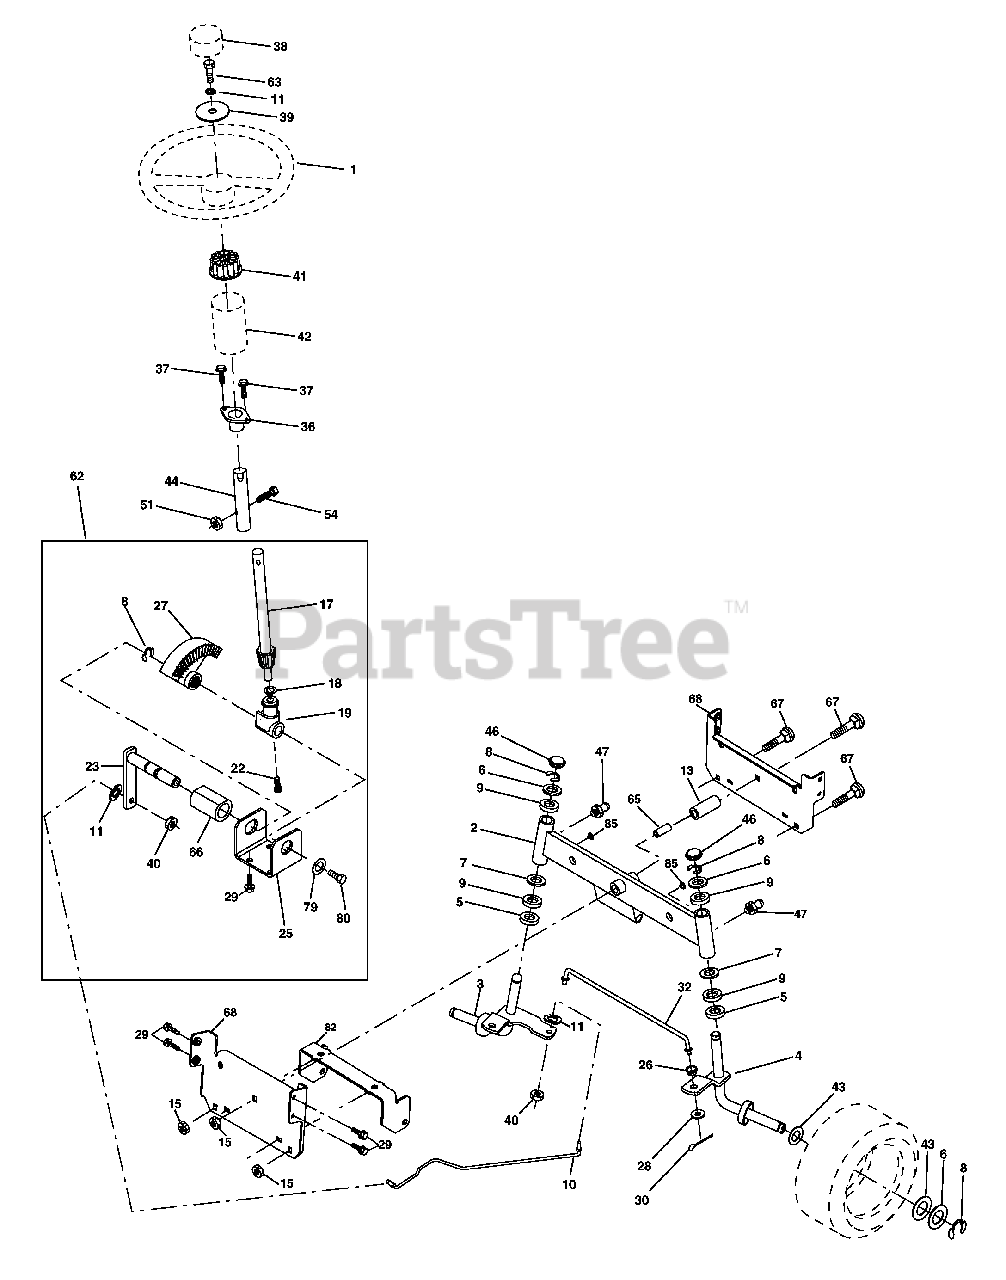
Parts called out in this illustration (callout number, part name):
1	Wheel Steering Ayp/P/L Blk
2	Axle Asm
3	Spindle Asm LH
4	Spindle Asm RH
5	Bearing Race Thrust Harden
6	Washer 25/32 X 1-5/8 X 16 Ga
7	Washer 27/32 X 1-1/4 X 16 Ga
8	Ring Klip #t5304-75
9	Bearing Col Strg Blk
10	Link Drag Extended Stamped
11	Washer Lock Hvy Hlcl Spr 3/8
13	Bearing Axle
15	Nut Lock Flange 5/8-11 Unc
17	Shaft Asm Strg
18	Washer Thrust 515x 750x 033
19	Support Shaft
20	Washer Shim 1/4 X 5/8 X 062
22	Screw Hex Socket 1/4-20 x 5/8
23	Shaft Asm Pittman
25	Bracket Steering
26	Bushing Link Drag Blk LR
27	Gear Sector
28	Washer 13/32 X 7/8 X 16 Ga
29	Screw Thdrol 3/8-16x3/4 Ty-tt
30	Pin Cotter 1/8 X 3/4 Cad
32	Rod Tie Wire Form 19 75 Mech
36	Bushing Strg 5/8 Id Dash
38	Cap Wheel Steer Ayp
39	Washer 13/32 X 2-3/8 X 8 Ga
40	Nut Lock Center 3/8-24un
41	Adaptor Wheel Strg
42	Boot Dash Mtl Steering Blk
43	Washer 25/32 X 1 1/4 X 16 Ga
44	Extension Steering
46	Cap Spindle Fr Top Blk
47	Fitting Grease
51	Nut Lock Hex W/Ins 5/16-18
54	Bolt Fin Hex 3/8-16unc x 1-1/4
62	Kit Steering Assembly Service
63	Bolt Fin Hex 3/8-16unc x 1 Gr.5
65	Spacer Axle
66	Bearing Arm Pittman
67	Bolt Fin Hex 5/8-11 unc x 2-3/4
68	Brace Axle
